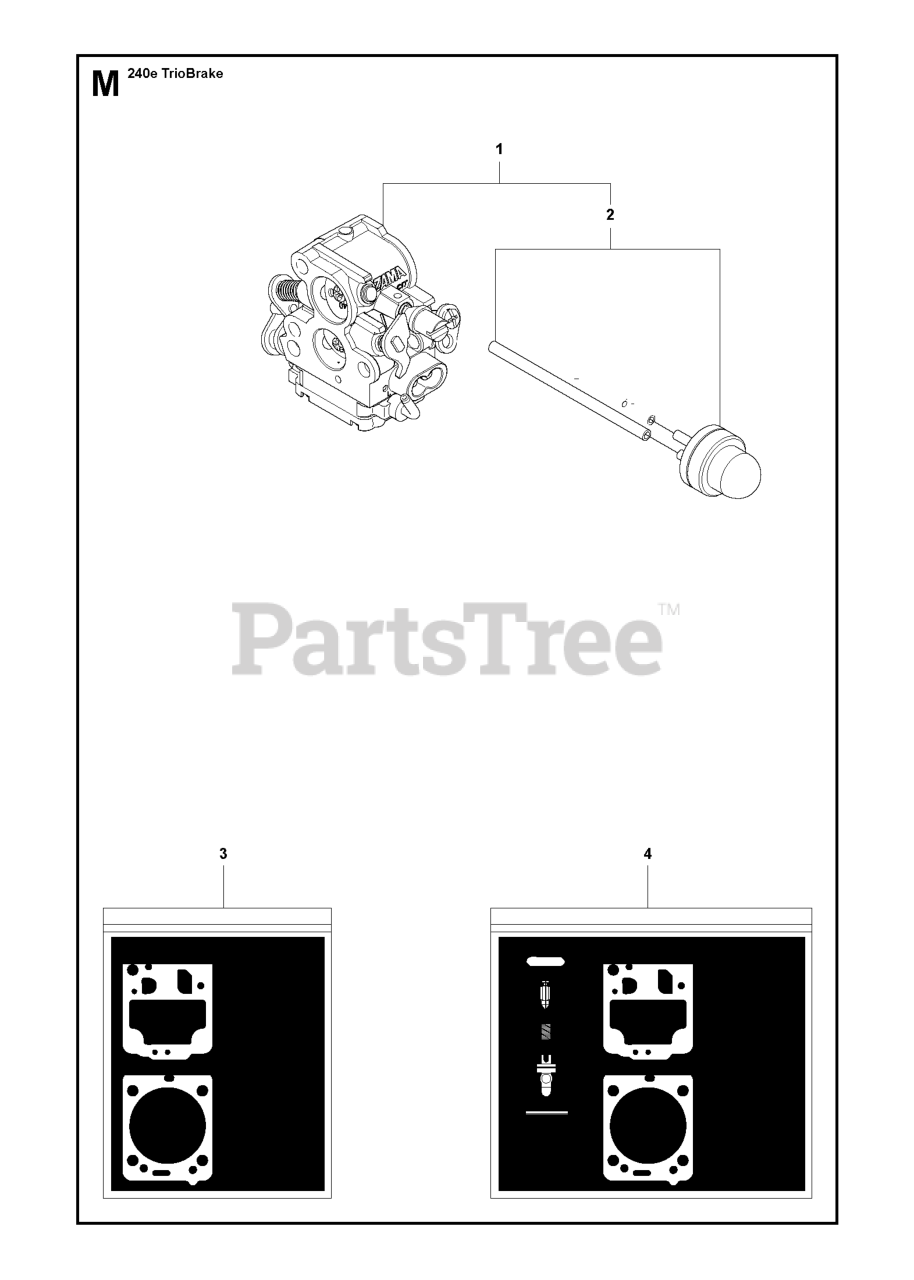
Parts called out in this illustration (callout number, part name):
1	CARBURETTOR 14MM AIR BORE, ANG
2	PURGE & LINE ASSY
3	KIT CARB GASKET
4	KIT CARB REPAIR
